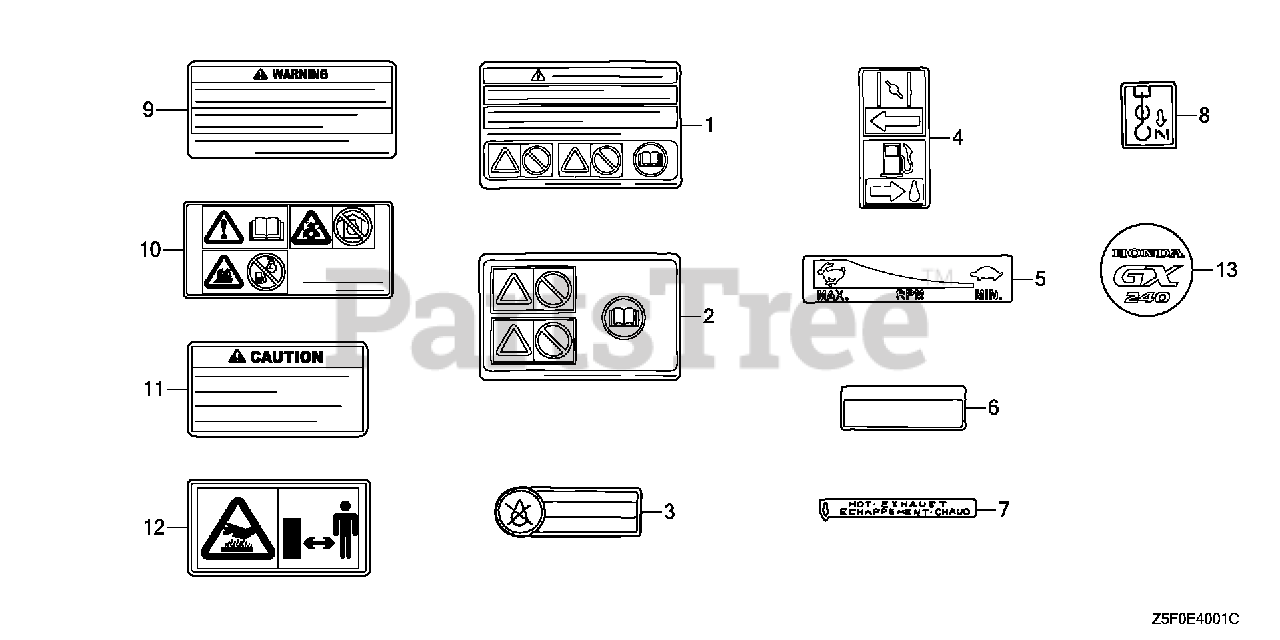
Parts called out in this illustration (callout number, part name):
1	MARK, OPERATOR CAUTION (FRENCH)(MADE IN JAPAN)
9	MARK, OPERATOR CAUTION (ENGLISH)(MADE IN JAPAN)
9	MARK, OPERATOR CAUTION (FRENCH)(MADE IN JAPAN)
11	MARK, EX. CAUTION (ENGLISH)
11	MARK, EX. CAUTION (FRENCH)
